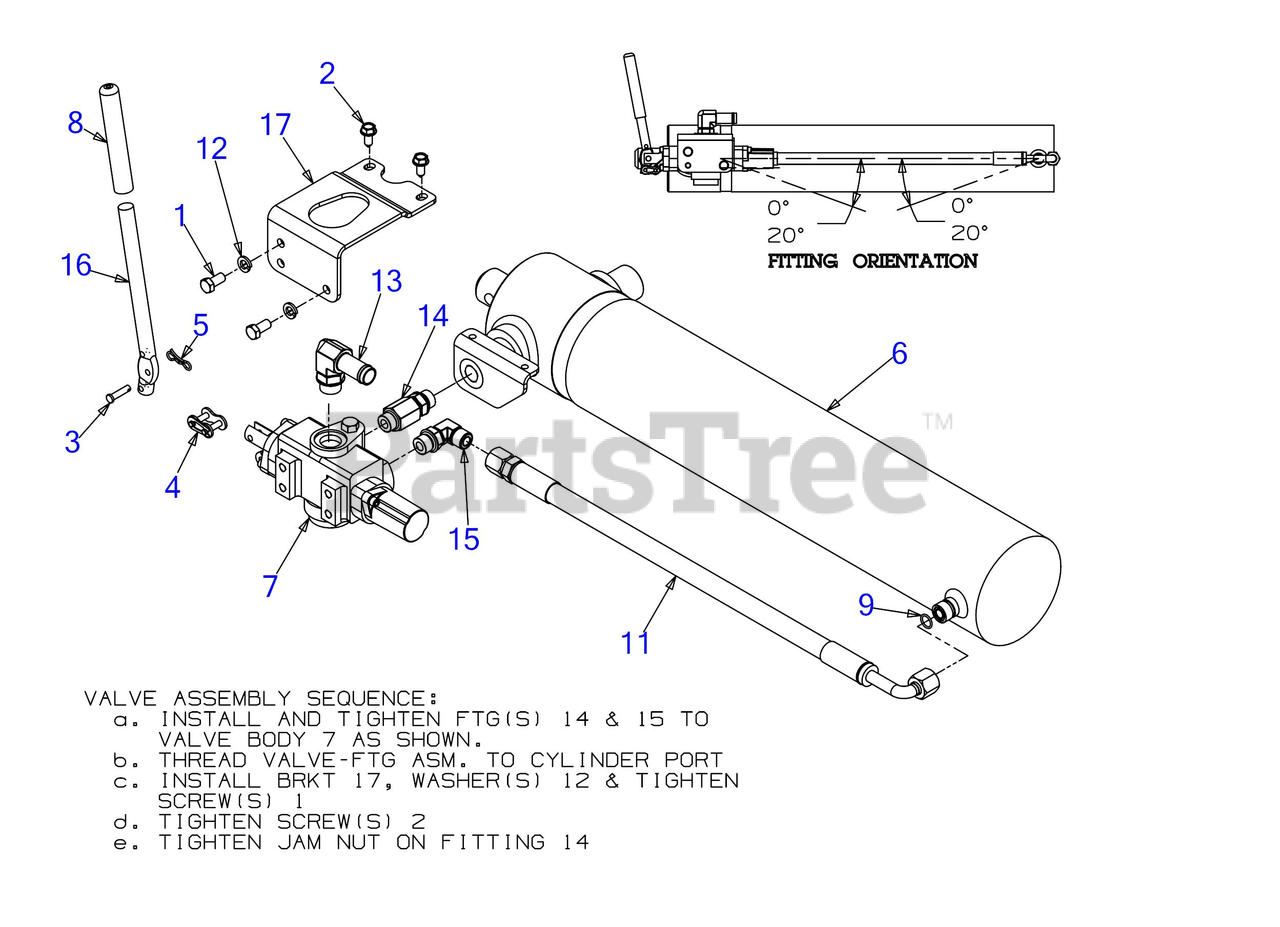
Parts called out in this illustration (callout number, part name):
1	HEX SCREW 3/8-16 x .75
2	SCREW 5/16-18 x .750
3	CLEVIS PIN .25 x 1.00
4	VALVE HANDLE LINK
5	BOW TIE COTTER PIN 1/4-5/16
6	HYDRAULIC CYLINDER
7	LOGSPLITTER VALVE
9	O-RING
11	HYDRAULIC HOSE
12	LOCK WASHER 3/8
13	HYDRAULIC FITTING
14	HYDRAULIC FITTING
15	HYDRAULIC FITTING
16	CONTROL VALVE HANDLE
17	VALVE BRACKET
